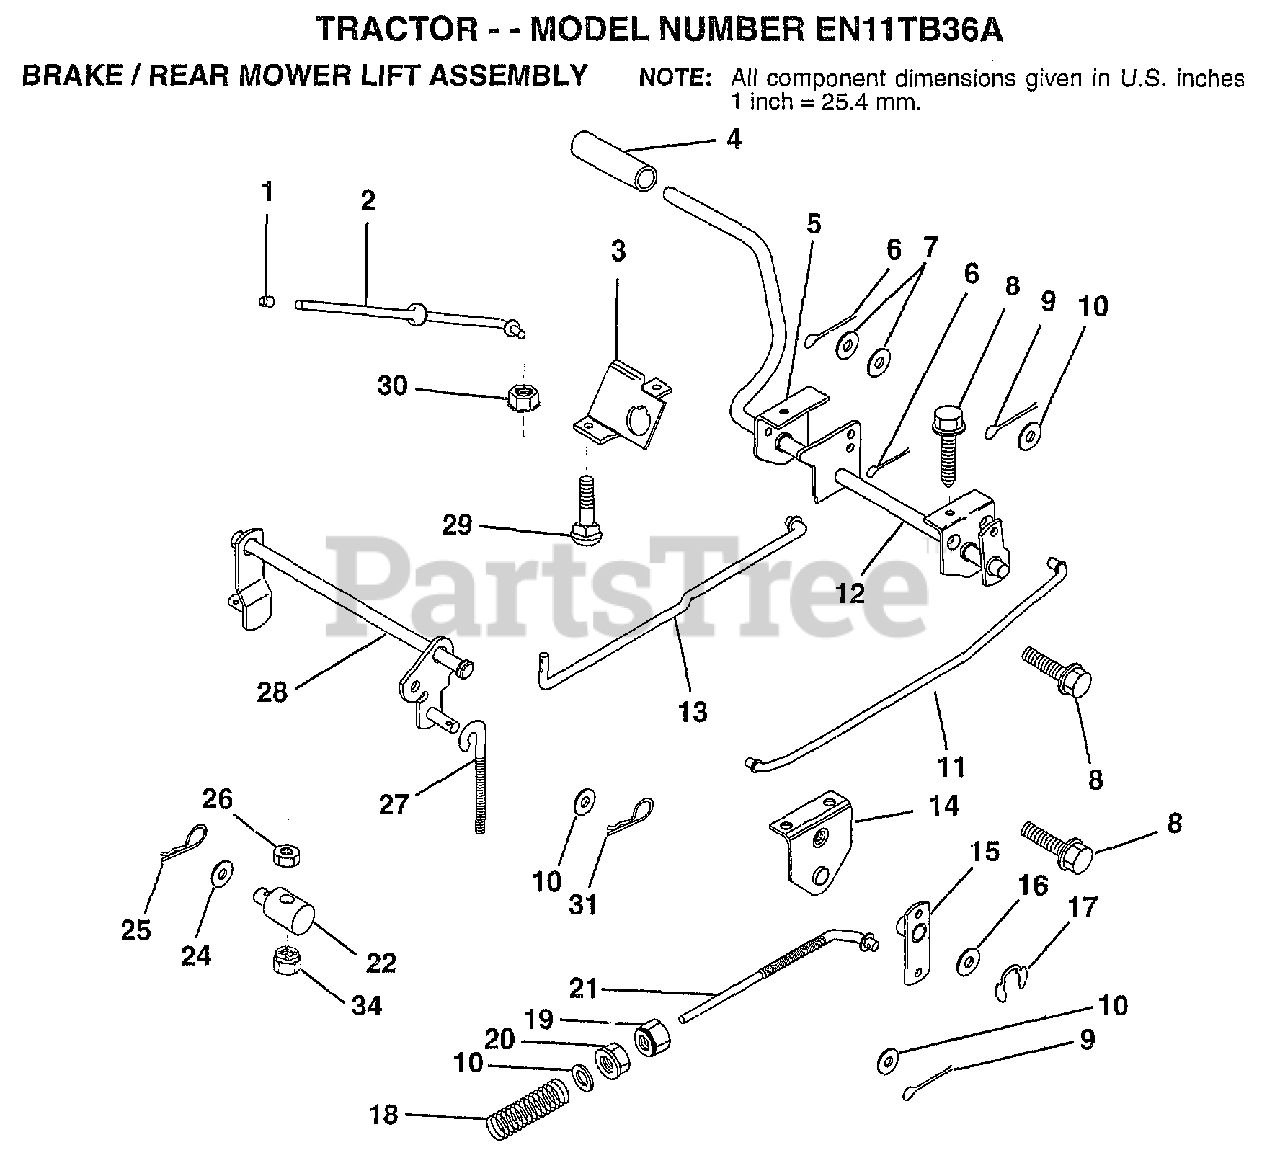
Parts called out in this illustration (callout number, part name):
1	PLUNGER CAP T
2	"ROD,PARK BRAKE"
3	"BRKT,PARK BRAKE"
4	FOOT PEDAL COVER
5	"BRKT,CLU PEDAL LH"
7	WASHER
8	SCREW LT
9	COTTER PIN
10	WASHER
11	"ROD,FRT BRAKE"
12	PEDAL ASM CL/BK36
13	"ROD,CLUTCH"
14	"BRKT,LIFT SHAFT"
15	PVT BRAKE ARM ASM
16	WASHER T
17	KLIP RING
18	SPRING ROD BRAKE
19	NUT
20	NUT
22	TRUNNION.LIFT.
24	WASHER
25	SPRING.RETAINER
26	LOCKNUT
27	"LINK, MOWER REAR"
28	LIFT ASM MOW REAR
31	RETAINER.SPRING
